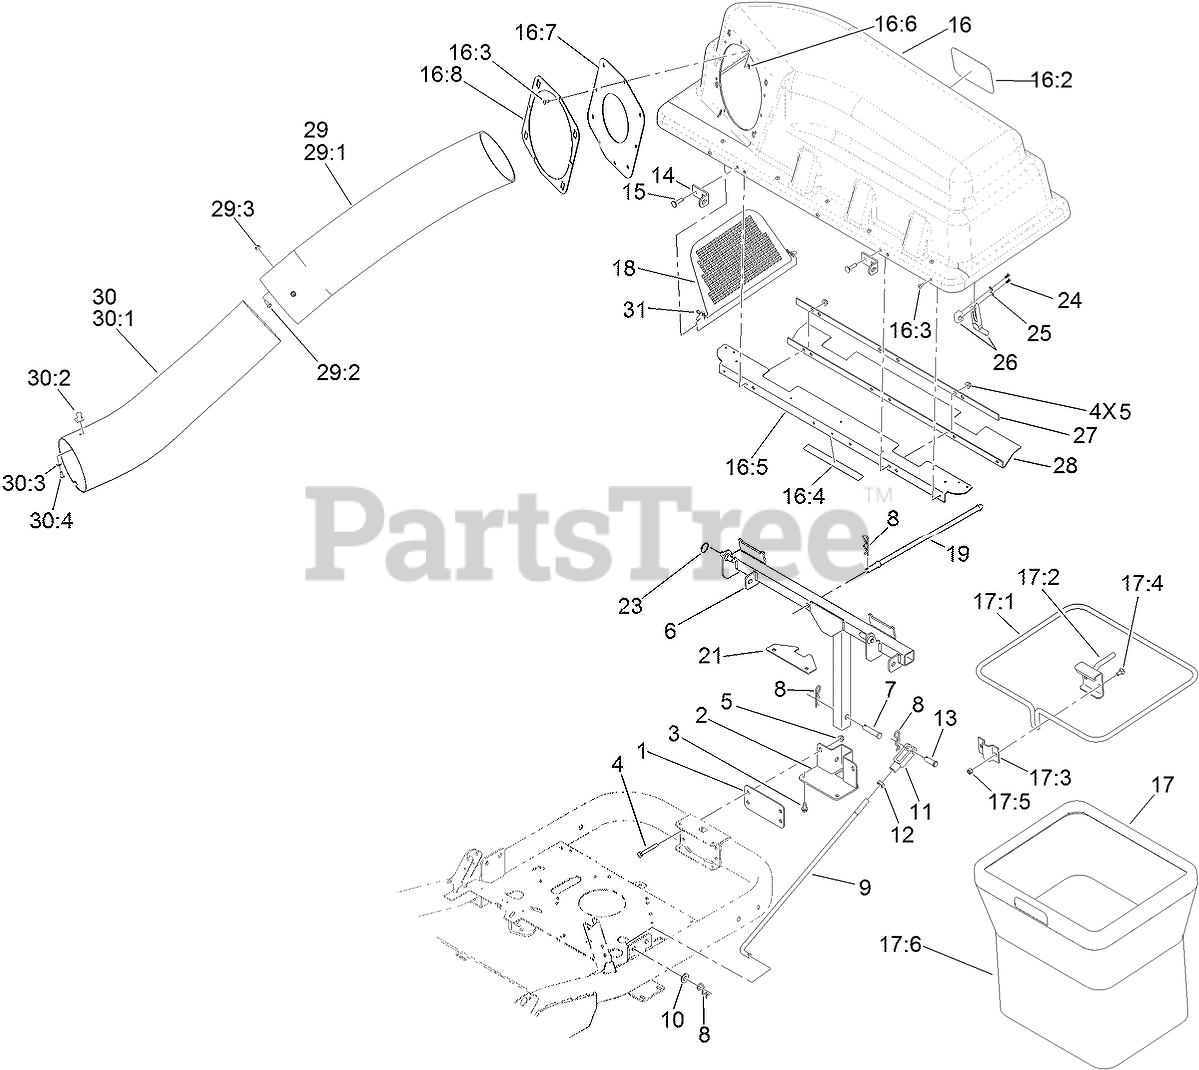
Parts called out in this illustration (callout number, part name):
2	SUPPORT-BAGGER
3	SCREW-HWHTF
4	SCREW-HH
5	NUT-HF, NI
6	PIVOT FRAME ASM
7	PIN-CLEVIS
8	PIN-HAIR
9	ROD-BAGGER
10	WASHER-FLAT
11	CLEVIS
12	NUT-JAM
13	PIN-CLEVIS
14	BRACKET-PIVOT, HOPPER
15	SCREW-CARR
16	BAGGER HOOD ASM
16:2	DECAL
16:3	RIVET-BLIND
16:4	DECAL-CAUTION, BAGGER
16:5	STIFFENER-BAGGER, TOP
16:6	WASHER-FLAT
16:7	GASKET
16:8	RING-RETAINER
17	BAG ASM
17:1	FRAME-BAG
17:2	HANGER ASM
17:4	BOLT-CARR
17:5	NUT-LOCK, NI
18	SCREEN-BAGGER
19	ROD-HOLD DOWN, HOOD
21	PLATE-SPACER
23	PIN-COTTER, CIRCULAR
24	SCREW-PLASTITE
25	WASHER-FLAT
26	LATCH-RUBBER
27	PLATE-BACKING
29	UPPER TUBE ASM
29:1	TUBE-UPPER
29:3	NUT-HF
30	LOWER TUBE ASM
30:1	TUBE-LOWER
30:2	LATCH-KEEPER
30:3	WASHER-FLAT
30:4	SCREW-PPH
31	PIN-COTTER
